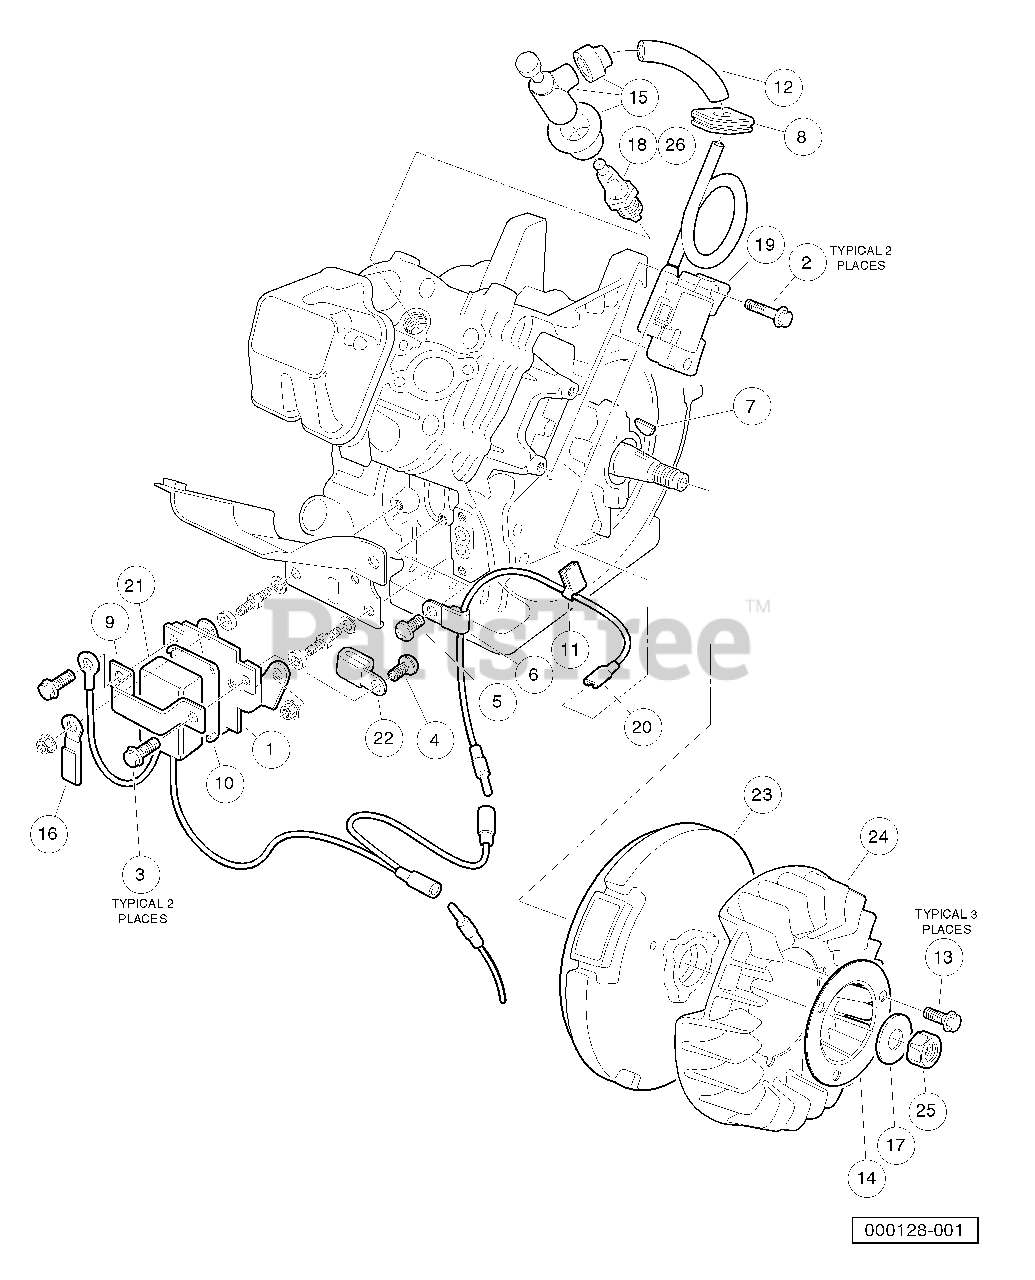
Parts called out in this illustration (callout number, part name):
1	Bracket, RPM Limiter
2	Bolt, Flange Head
3	Bolt, Flange Head, M6 x 1 x 12 mm
4	Screw, Pan WP Cross
9	Band, RPM Limiter Mount
10	Damper, RPM Limiter
12	Tube, 7mm X 10mm X 70mm
13	Bolt, Flanged
14	Plate, Flywheel Fan
15	Cap Asm Plug
17	Washer, Flat
18	Spark Plug, OHV
19	Coil, Ignition
20	Lead Wire Assy
21	Limited RPM
22	Clamp, Steel
24	Fan
25	Nut, Fine Hex, 18mm
26	Spark Plug, OHV
